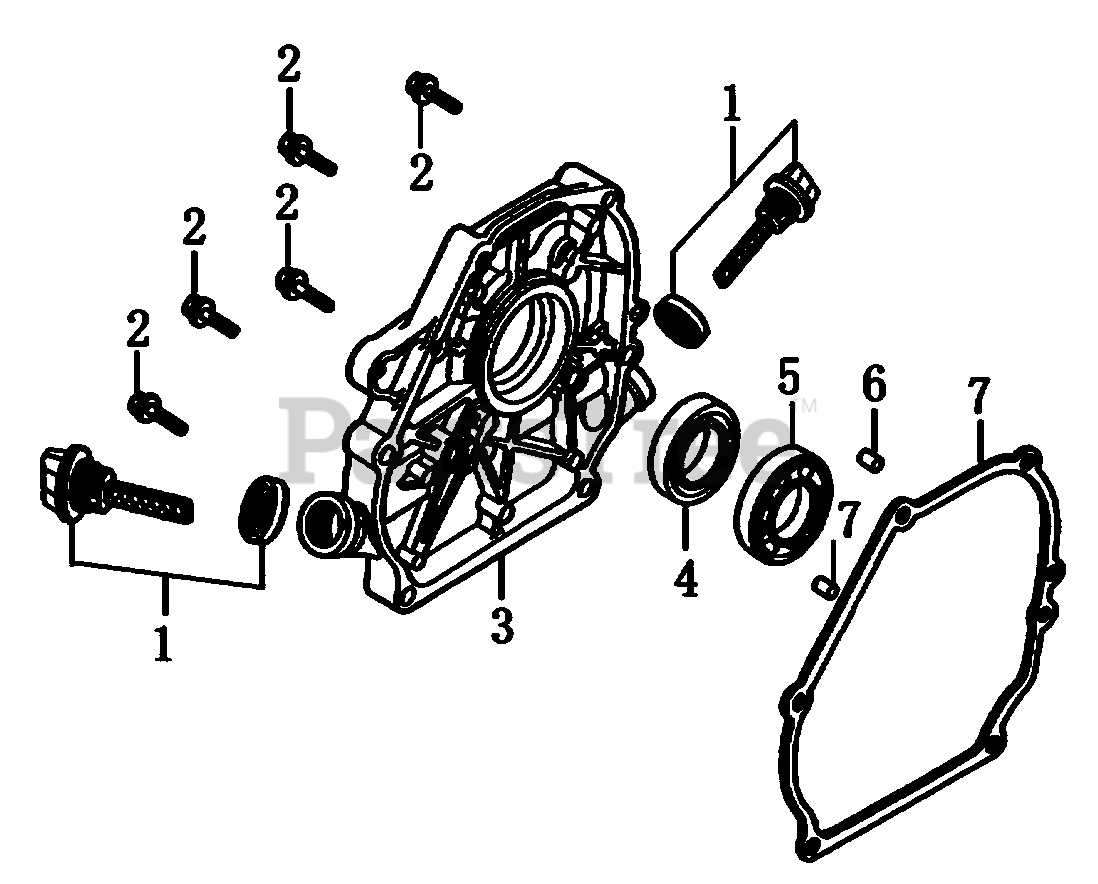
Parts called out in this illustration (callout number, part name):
1	GAUGE ASSY., OIL LEVEL
2	BOLT, FLANGE
3	CASE COVER
4	OIL SEAL 25X41.25X6
5	BEARING, RADIAL BALL
6	PIN, DOWEL
7	GASKET, CASE COVER
